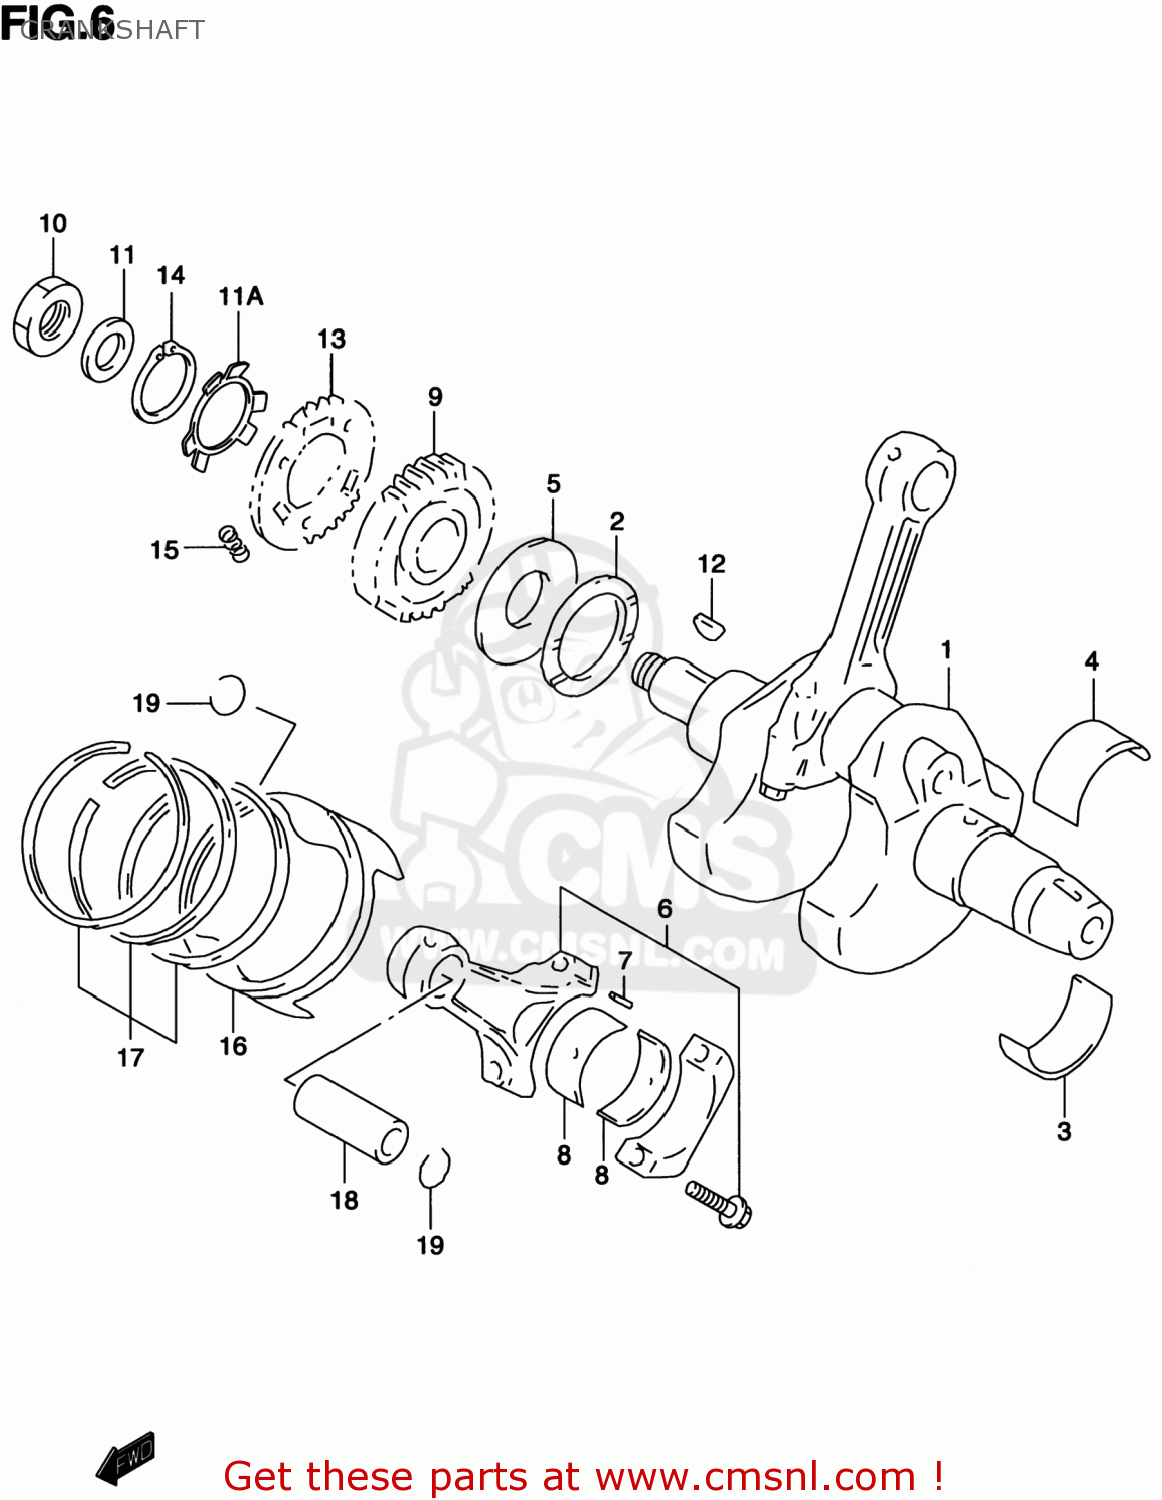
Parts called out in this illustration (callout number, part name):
1	CRANKSHAFT SET
2	WASHER(48.1X64X1.94)
3	BEARING,CRANKSHAFT
4	BEARING,CRANKSHAFT
5	WASHER,CRANK THRUST
6	CONNECTING ROD ASSY
7	PIN,CONNECTING ROD
8	BEARING,CRANK PIN
9	GEAR,PRIMARY DRIVE
10	NUT
11	WASHER
11A	WASHER,PRI DRIVE
12	KEY
13	GEAR,PRIMARY DRIVE SCISSORS
14	CIRCLIP
15	SPRING
16	PISTON
17	RING SET,PISTON
18	PIN,PISTON
19	CIRCLIP
